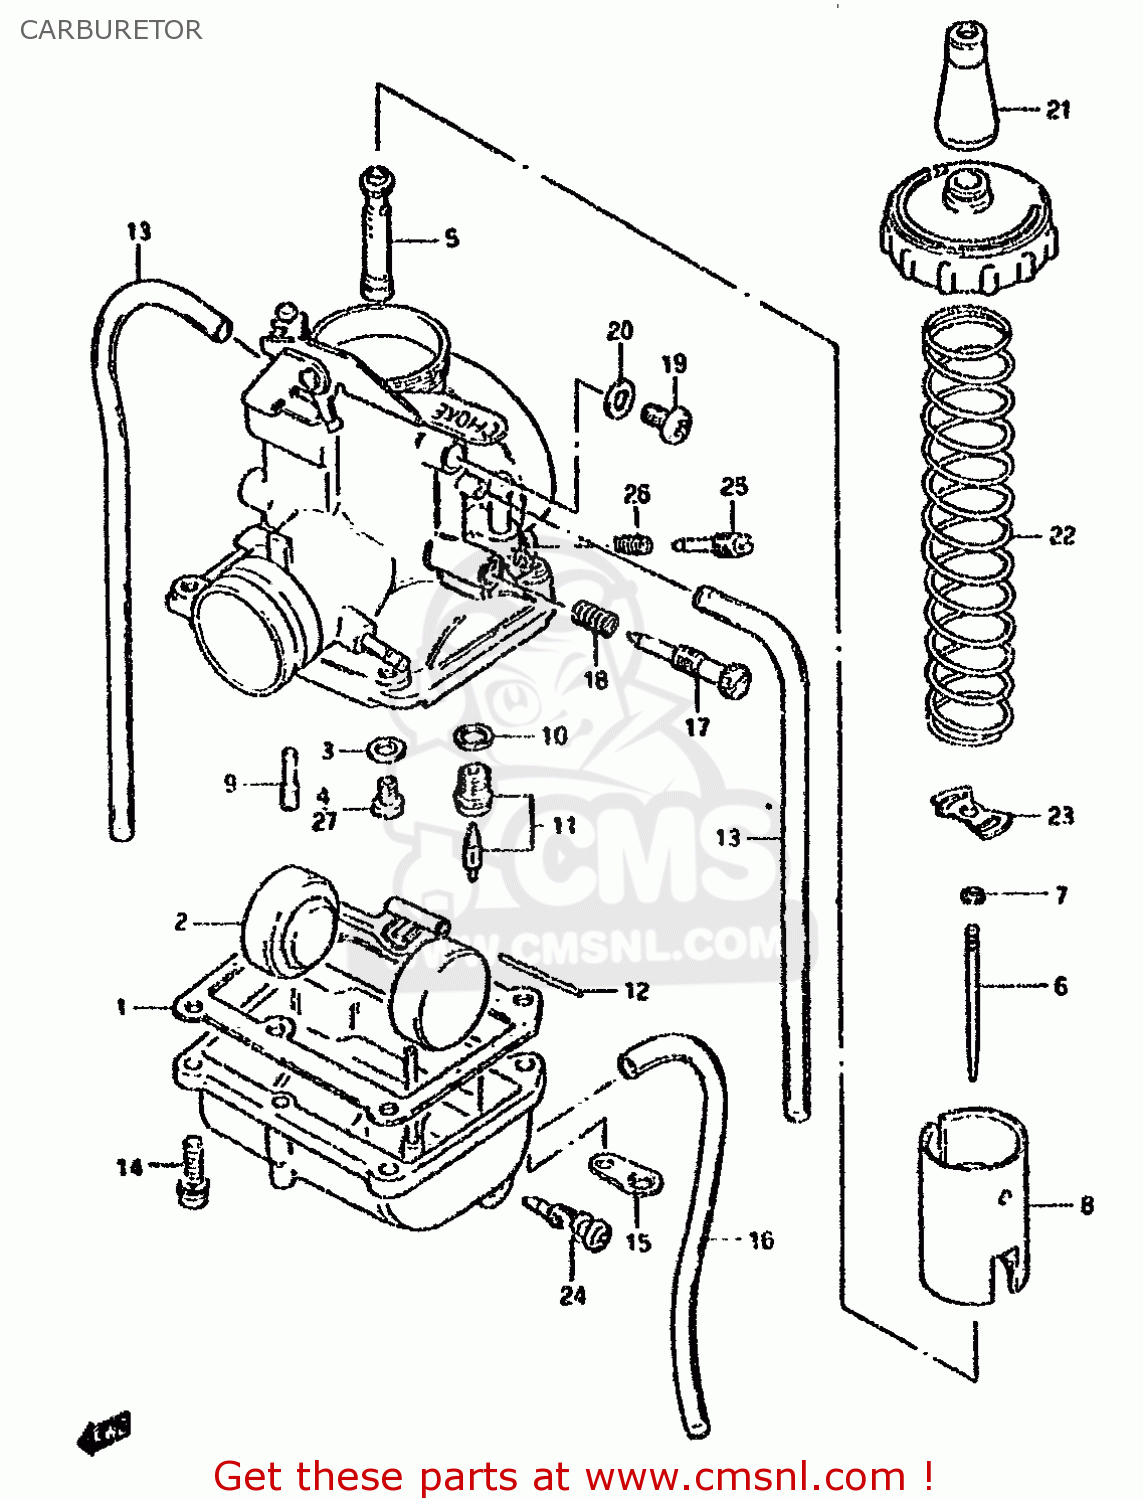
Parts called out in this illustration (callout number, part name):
1	GASKET,FLOAT CHAMBER (NAS)
2	FLOAT
3	WASHER,NEEDLE NOZZLE
4	JET,MAIN(87.5)
5	JET,NEEDLE
6	NEEDLE,JET
7	CLIP
8	VALVE,THROTTLE
9	JET,PILOT(25)
10	GASKET,NEEDLE VALVE (NAS)
11	VALVE ASSY,NEEDLE
12	PIN,FLOAT
13	HOSE
14	SCREW
15	PLATE
16	HOSE(3X5X650)
17	SCREW,THROTTLE STOP
18	SPRING
19	SCREW
20	GASKET,DRAIN PLUG (NAS)
21	CAP,CABLE ADJUSTER
22	SPRING,THROTTLE VALVE
23	STOPPER,NEEDLE CLIP
24	PLUG,DRAIN
25	SCREW,PILOT AIR
26	SPRING
27	JET,MAIN
